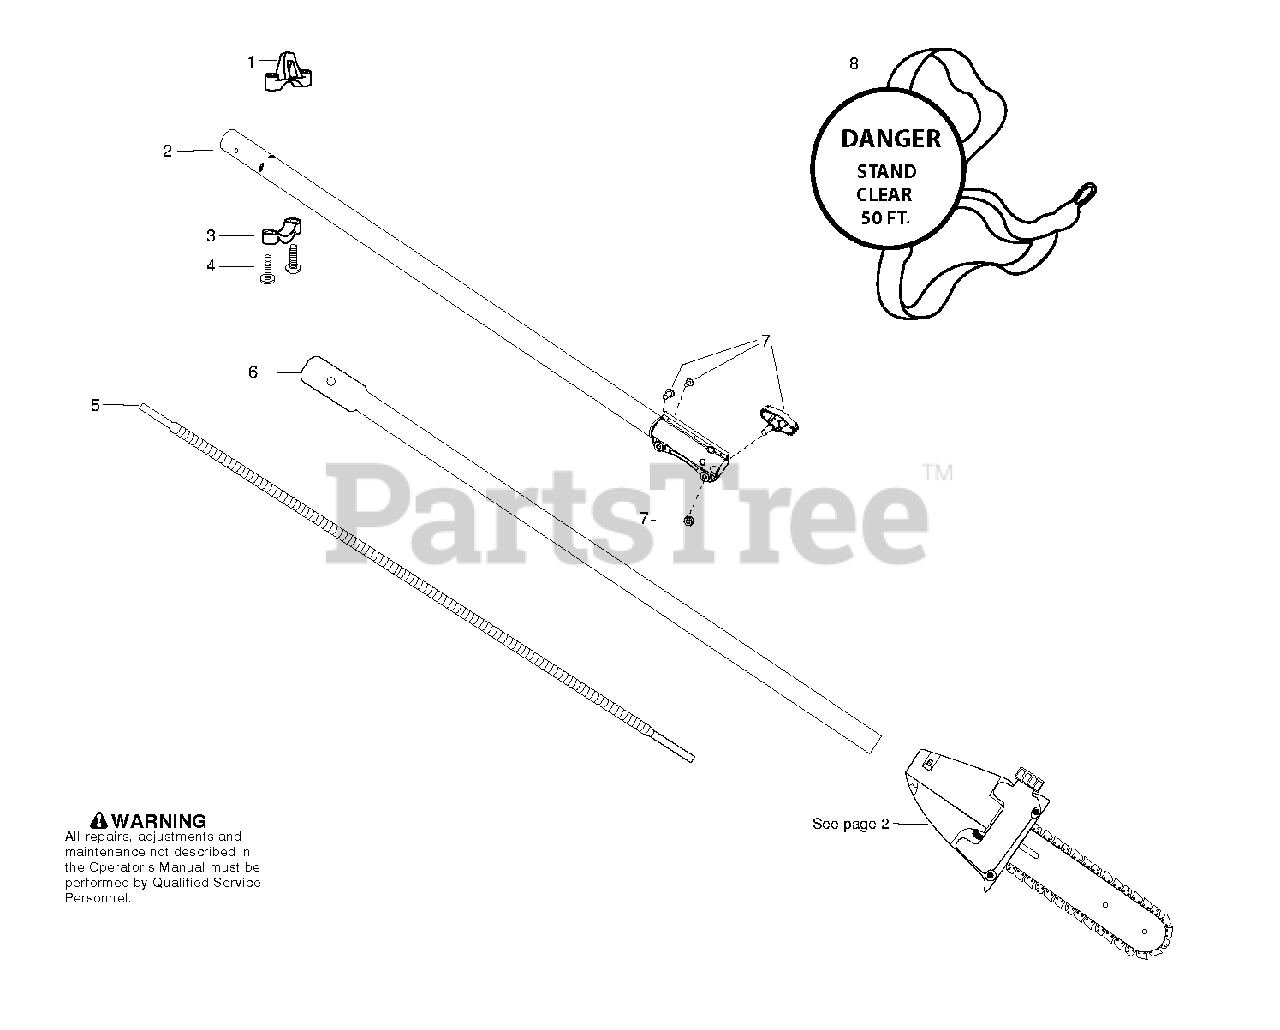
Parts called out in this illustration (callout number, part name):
1	CLAMP HARNESS - UPPER
2	TUBE
3	CLAMP HARNESS - LOWER
4	SCREW #10 PLASTITE 1.362
5	FLEX-LOWER
7	ASSY COUPLER BLACK
8	ASSY,SHOULDER STRAP
